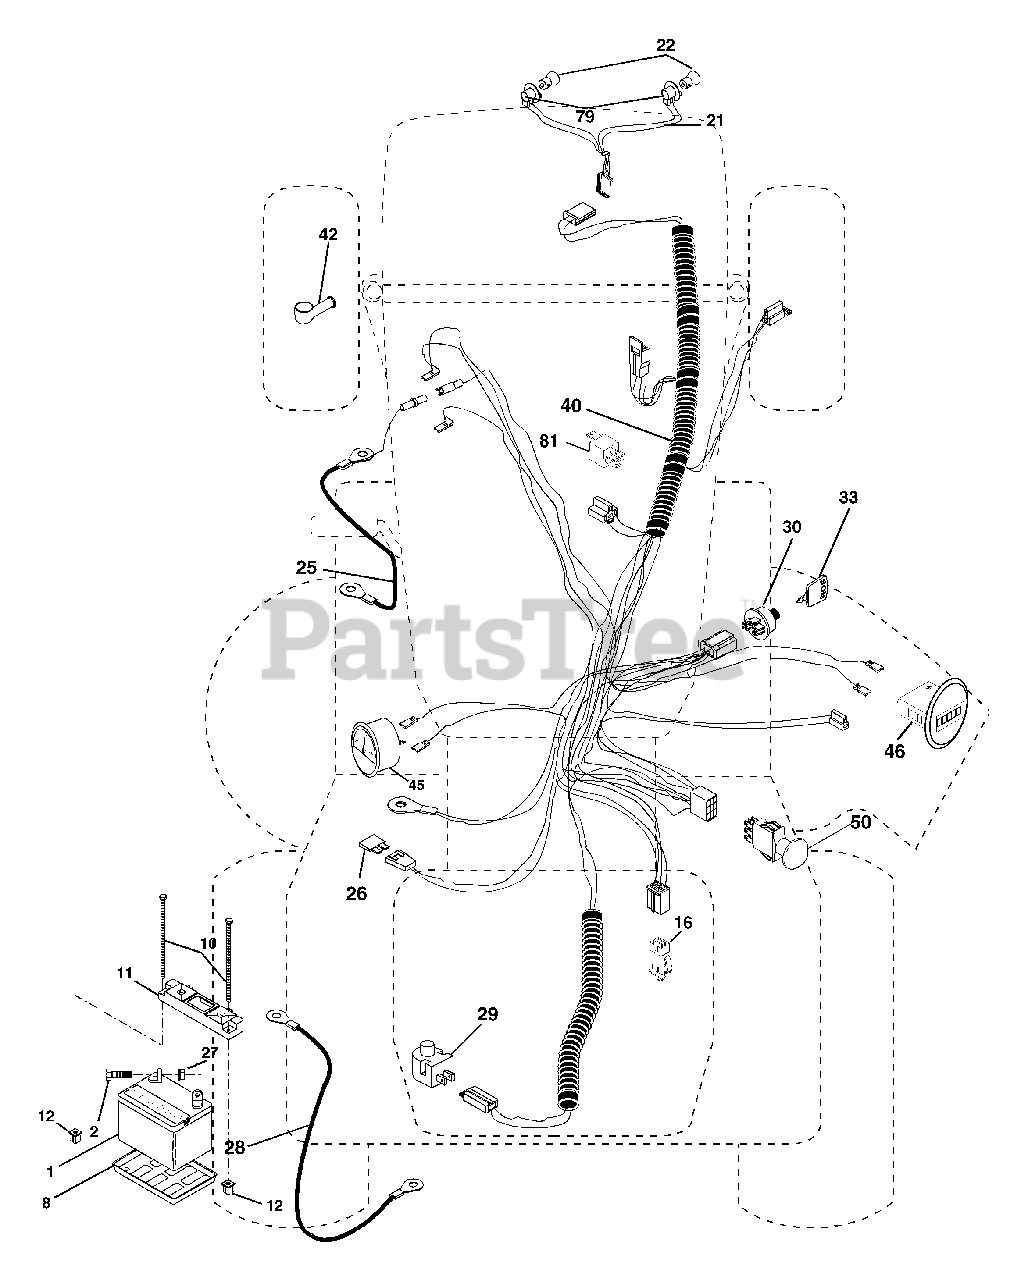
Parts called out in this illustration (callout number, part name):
1	Battery
2	Bolt Hex Head 1/4-20 x 3/4
8	Tray, Battery
10	Bolt, Battery Front 1/4-20 x 7.5 Zinc
11	Holddown Battery Front Mount
12	Nut, Push Nylon 1.4" Battery Front
16	Switch Interlock Push-In
21	Harness Socket Light w/4152J
25	Cable, Battery
27	Nut Keps Hex 1/4-20
28	Cable, Ground
29	Switch, Plunger NC Gray
30	Switch, Ign
40	Harness Ign.
42	Cover, Terminal Red
50	Switch, PTO
79	Socket Assembly Bulb
81	Relay Asm.
